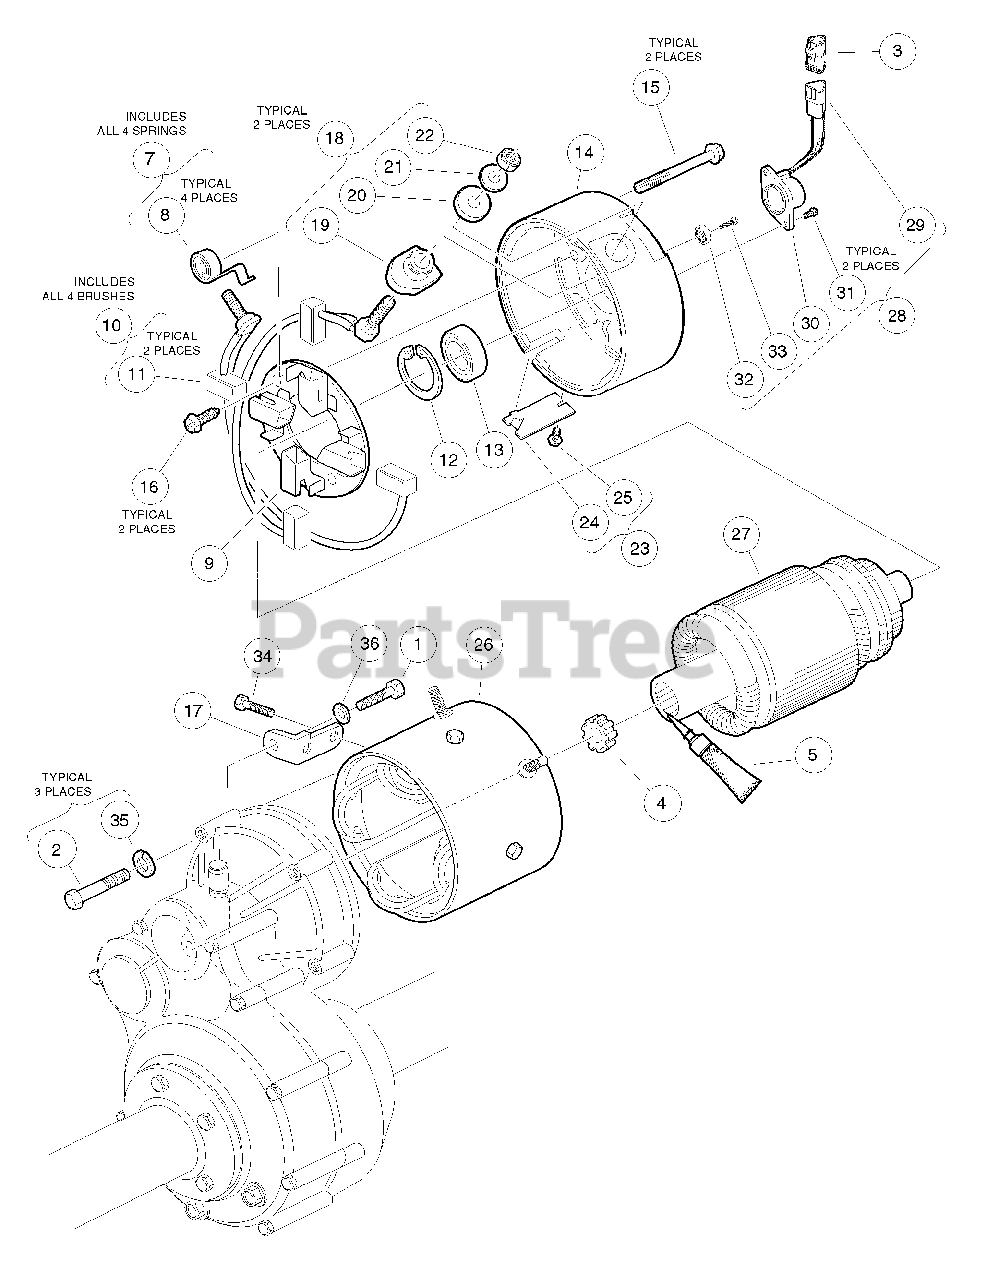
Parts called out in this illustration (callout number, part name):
1	Screw, 5/16-18 X 1.00 Hex Cap
2	Screw, 1/4-20 X 2.25 Hex Cap
3	Kit, 3-Pin Wedge Lock
4	Bumper, Drive Unit
5	Lubricant, Moly-Teflon
6	IQ Electric Motor, 48-VDC 3.3 hp
7	Spring Kit, Motor Brush
8	Spring, Brush, S-g
9	Brush Box Assembly
10	Brush Kit, Motor
11	Assembly, Brush and Terminal
12	Ring, 2.24" Internal Retaining
13	Bearing, Ball
14	End Cap, Motor
15	Screw, 1/4-20 X 2.25 Hex-Head Washer
16	Screw, #8-32 X .5 Hex-Head
17	L-Bracket, Motor
18	Hardware Kit, Motor Terminal
19	Bushing, Nylon
20	Washer, Nylon Flat
21	Washer, Flat, 5/16 Steel
23	Plate Kit, Motor Cover
24	Assembly, Cover Plate
25	Screw, #8-32 x 0.375, Taptite Thread
26	Frame and Field Assembly
27	Armature Assembly
28	Kit, Speed Sensor
29	Kit, 3-Pin Wedge Lock
30	Sensor, Motor Speed, ADC
31	Screw, #8-32, Taptite Thread
32	Magnet, ADC Motor
34	Bolt, 1/4 - 20 x 0.73 Thread-Forming
35	Lockwasher, 1/4 Helical Split
36	Lockwasher, 5/16 Split
